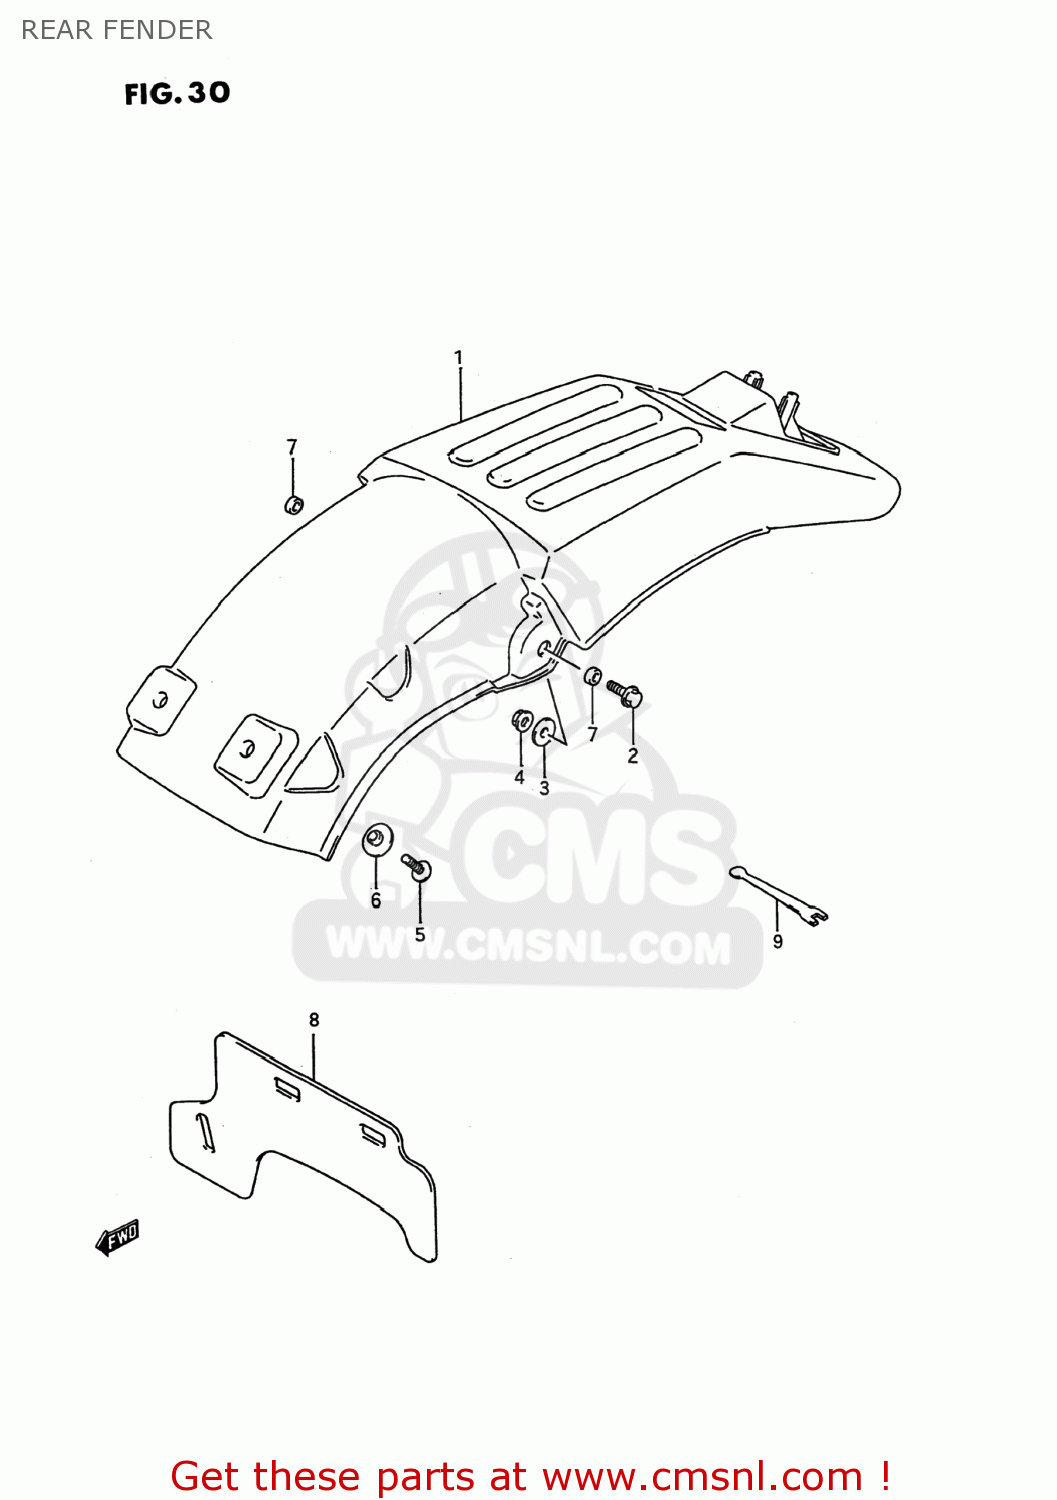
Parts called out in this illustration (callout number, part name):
1	BODY,RR FENDER
2	BOLT
3	WASHER(8.5X20X1.6)
4	NUT
5	SCREW
6	WASHER
7	SPACER (8.8X12X4)
8	MUDGUARD,RR FENDER
9	SPANNER,OPEN
